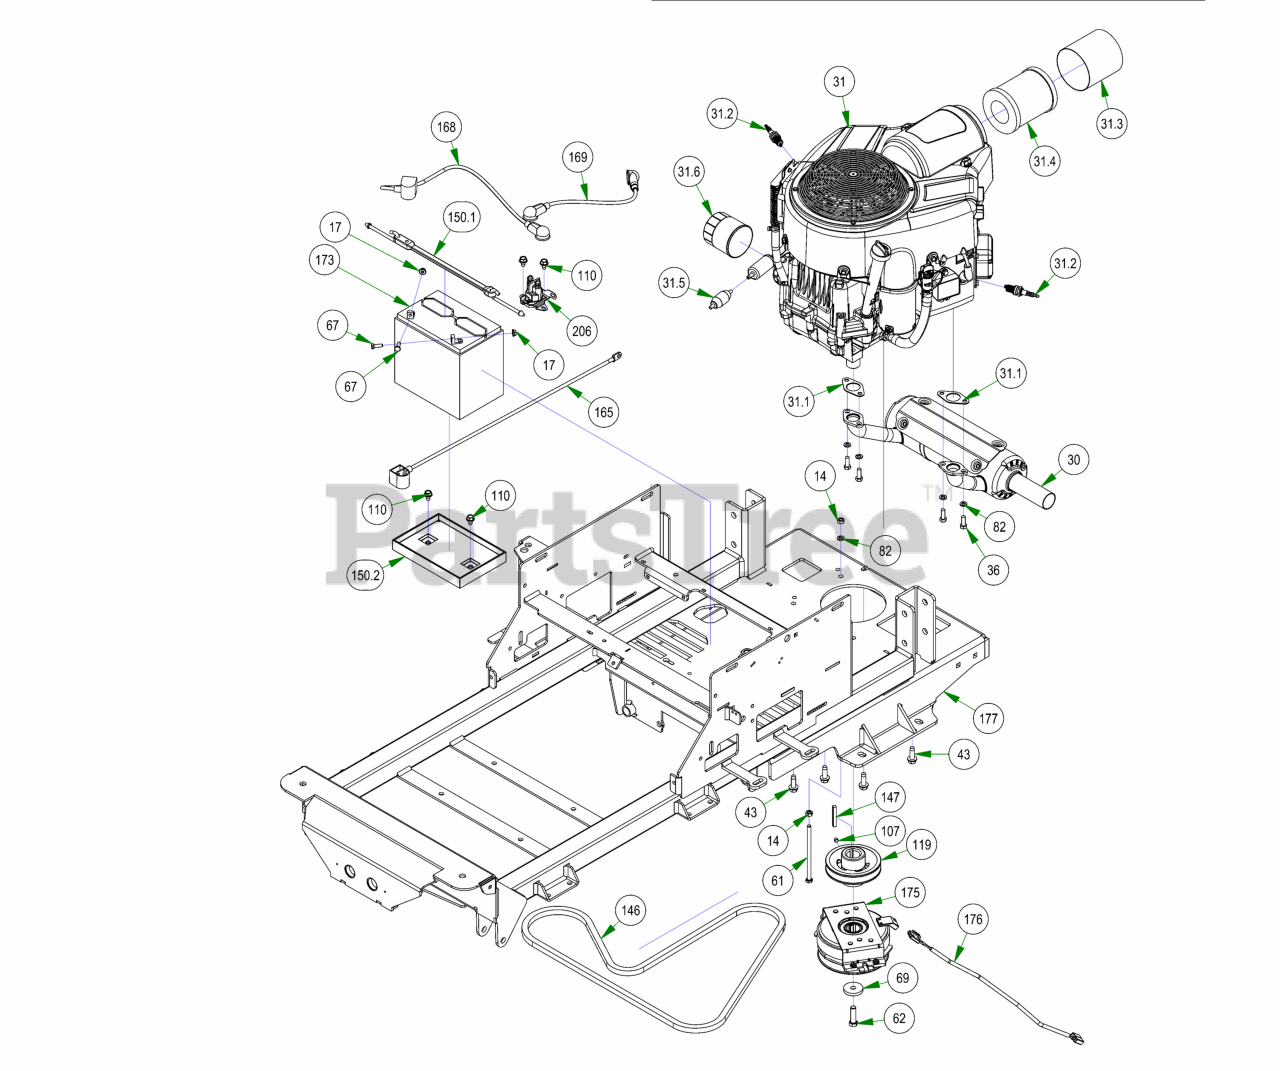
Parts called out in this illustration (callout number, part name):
14	5/16-18 HEX NUT ZINC
17	1/4-20 HEX SERRATED FLANGE NUT HARD/ZINC
30	2017 Compact Outlaw Exhaust 810 Vanguard
31	Vanguard 27hp CXI with Out Oil Filter Maverick
31.1	Exhaust Gasket
31.2	Spark Plug
31.3	pre-Cleaner for Vanguard CXI Engine
31.4	Air Filter for Vanguard CXI Engine
31.5	Universal Inline Fuel Filter
31.6	Oil Filter
36	Torx Bolt-Exhaust
43	3/8-16 X 1-1/8 HEX WASHER UNSLOT SERRATED (TRI-LOB) TRS ZINC YELLOW
61	5/16-18 X 5-1/2 HEX CAP SCREW (GR.5) ZINC
62	7/16-20 X 1-1/2 HEX CAP SCREW (GR.8) w/ Patch
67	1/4-20 X 3/4 HEX CAP SCREW (GR.5) ZINC
69	CLUTCH WASHER
82	5/16 SPLIT LOCKWASHER ZINC
107	5/16-24 X 1/4 SOCKET SET SCREW (CUP PT) PLAIN
110	5/16-18 X 1/2 HWH unslot (F) tcs zinc
119	4 3/4 Motor Pulley
146	75.8" Pump Belt
147	1/4 X 2 SQ MACHINERY KEY 1018 STL PLAIN
150	2023 Battery Hold Down Assembly Strap
150.1	2023 Rubber Battery Hold Down Strap
150.2	Battery Tray
165	24 inch Black Cable – MZ/ZT
168	24" Red Battery Cable
169	12" Red Battery Cable
173	SP-35 Battery
176	Clutch Pigtail
177	2023 Maverick Frame - Painted
